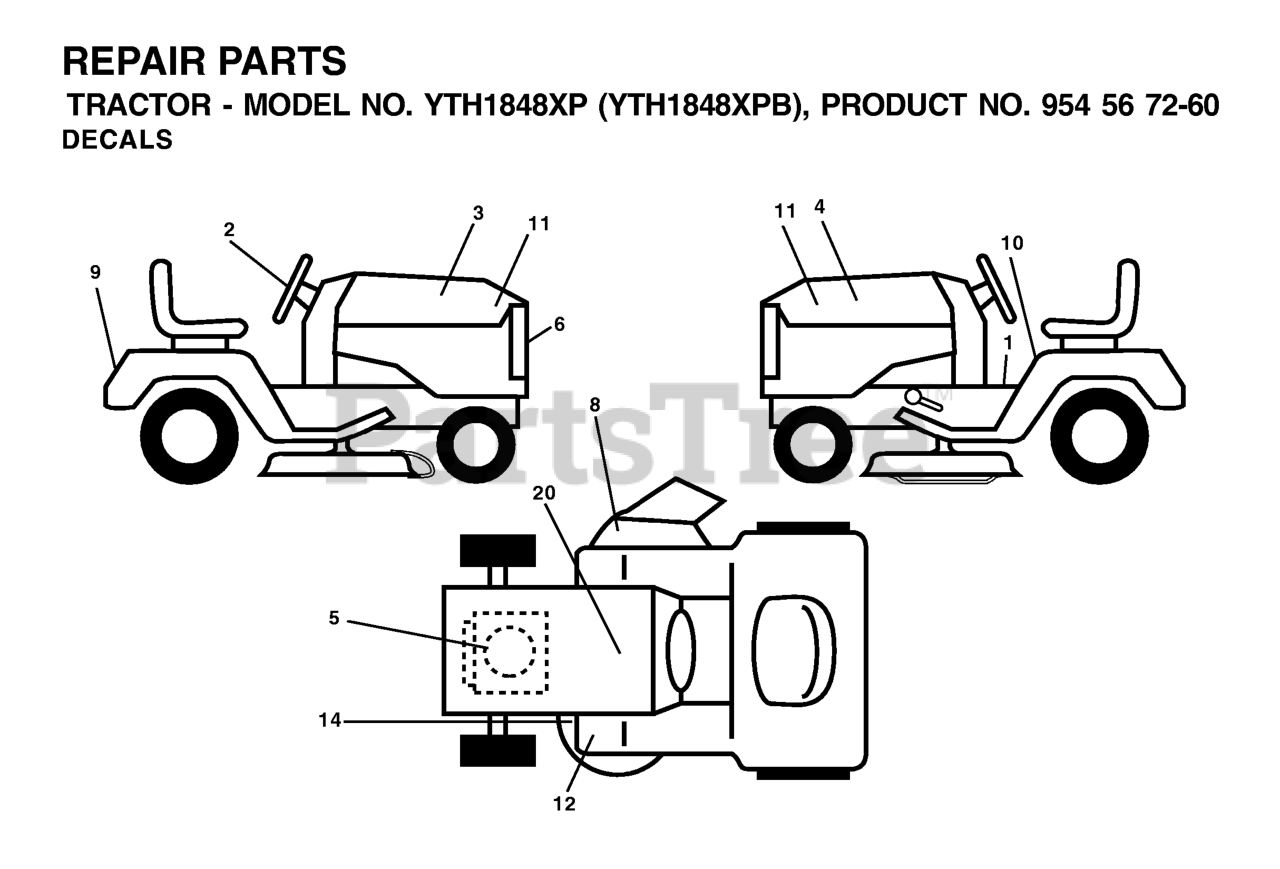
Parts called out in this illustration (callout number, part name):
2	DECAL.WHEEL.STEERING.HUSQ.PERM
3	HOOD DECAL
4	HOOD DECAL
5	DECAL ENGINE
6	DECAL.GRILLE.HUSQ
8	DECAL.WARN.KEEP.HAND.AWAY
9	DECAL, FENDER
10	DECAL FENDER DANGER
11	DECAL HOOD
12	DECAL CLUTCH/BRAKE
14	DECAL V-BELT SCHEMATIC
20	DECAL BTRY SYMBOLS
